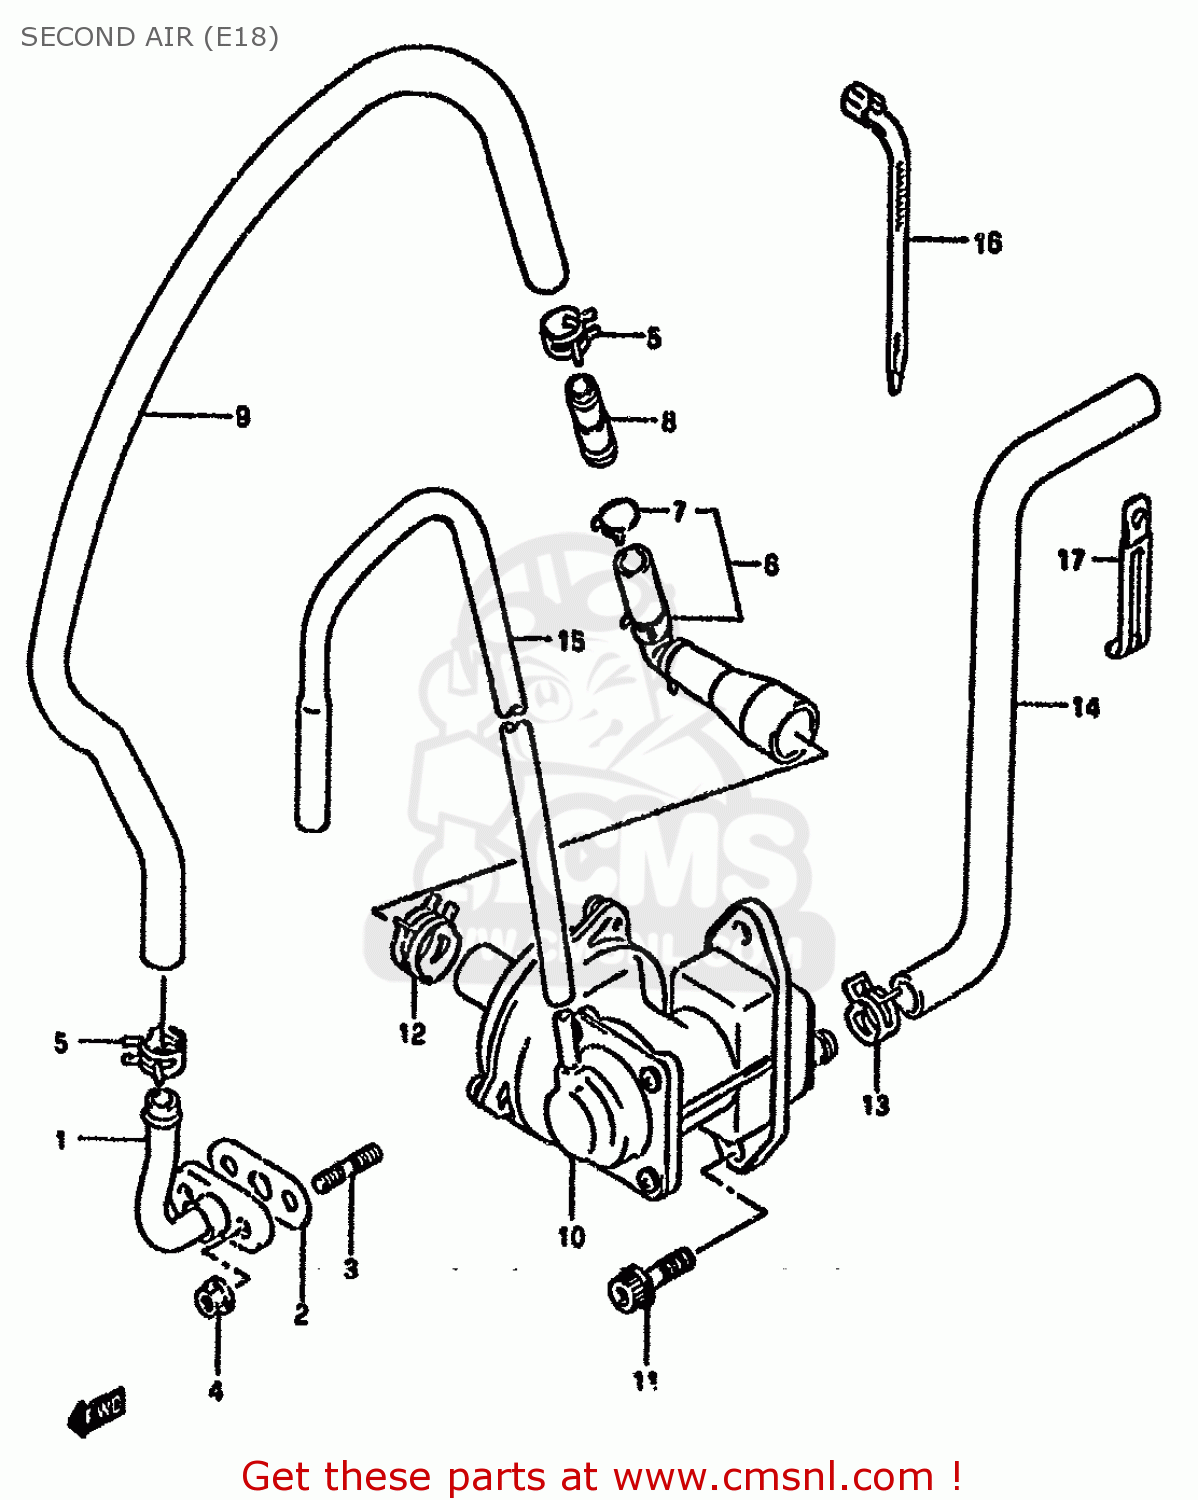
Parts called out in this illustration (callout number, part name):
1	PIPE,2ND AIR
2	GASKET,2ND AIR (NAS)
3	STUD 6X16
4	NUT 6MM
5	CLIP
6	HOSE ASSY
7	CLIP,BREATHER TUBE
8	UNION, 2ND AIR HOSE
9	HOSE,2ND AIR NO.2
10	VALVE ASSY,2ND AIR REED
11	PLUG ,6X20
12	CLIP
13	CLIP
14	HOSE,2ND AIR NO.4
15	HOSE,2ND AIR NO.3
16	CLAMP(L:165)
17	CLAMP
